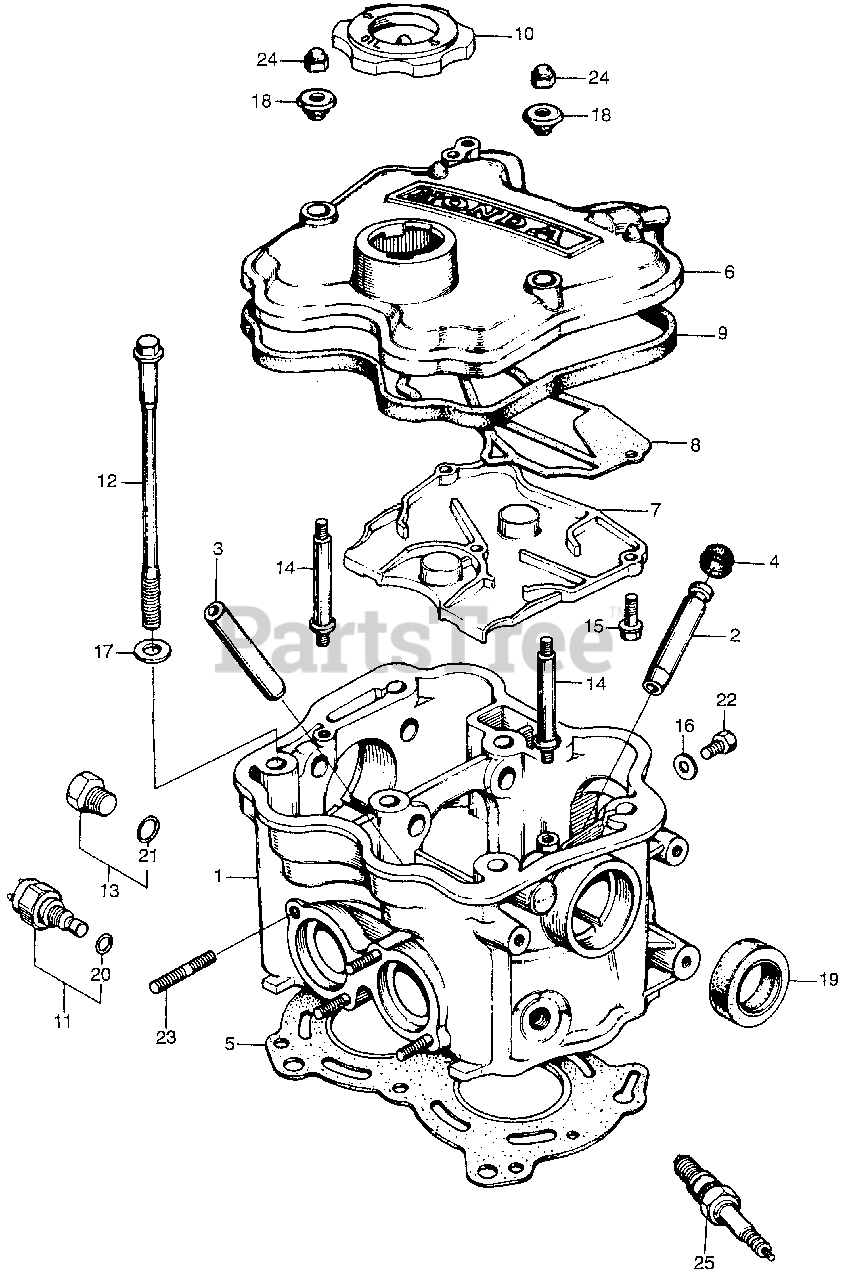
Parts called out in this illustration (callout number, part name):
1	CYLINDER HEAD
2	GUIDE, VALVE
3	GUIDE, EX. VALVE
4	SEAL, VALVE STEM (NOK)
4	SEAL, VALVE STEM
5	GASKET, CYLINDER HEAD
6	COVER, CYLINDER HEAD
7	COVER, BREATHER (NOT AVAILABLE)
8	GASKET, BREATHER
9	GASKET, HEAD COVER
10	CAP ASSY., OIL FILLER
11	SWITCH, THERMOSTAT
12	BOLT, CYLINDER HEAD
12	BOLT, CYLINDER HEAD (NOT AVAILABLE)
13	BOLT, SEALING (18MM)
14	BOLT, HEAD COVER
15	SCREW, TAPPING (6X20)
16	WASHER (6MM)
17	WASHER, SPECIAL (23x11x2.3)
18	WASHER, HEAD COVER
19	OIL SEAL (27X43X9) (NOK)
19	OIL SEAL (27X43X9)
20	O-RING (13.5X1.4)
21	O-RING (15.5X1.4)
22	BOLT, HEX. (6X20)
23	BOLT, STUD (8X40)
24	NUT, CAP (6MM)
25	SPARK PLUG (B6E) (NGK)
